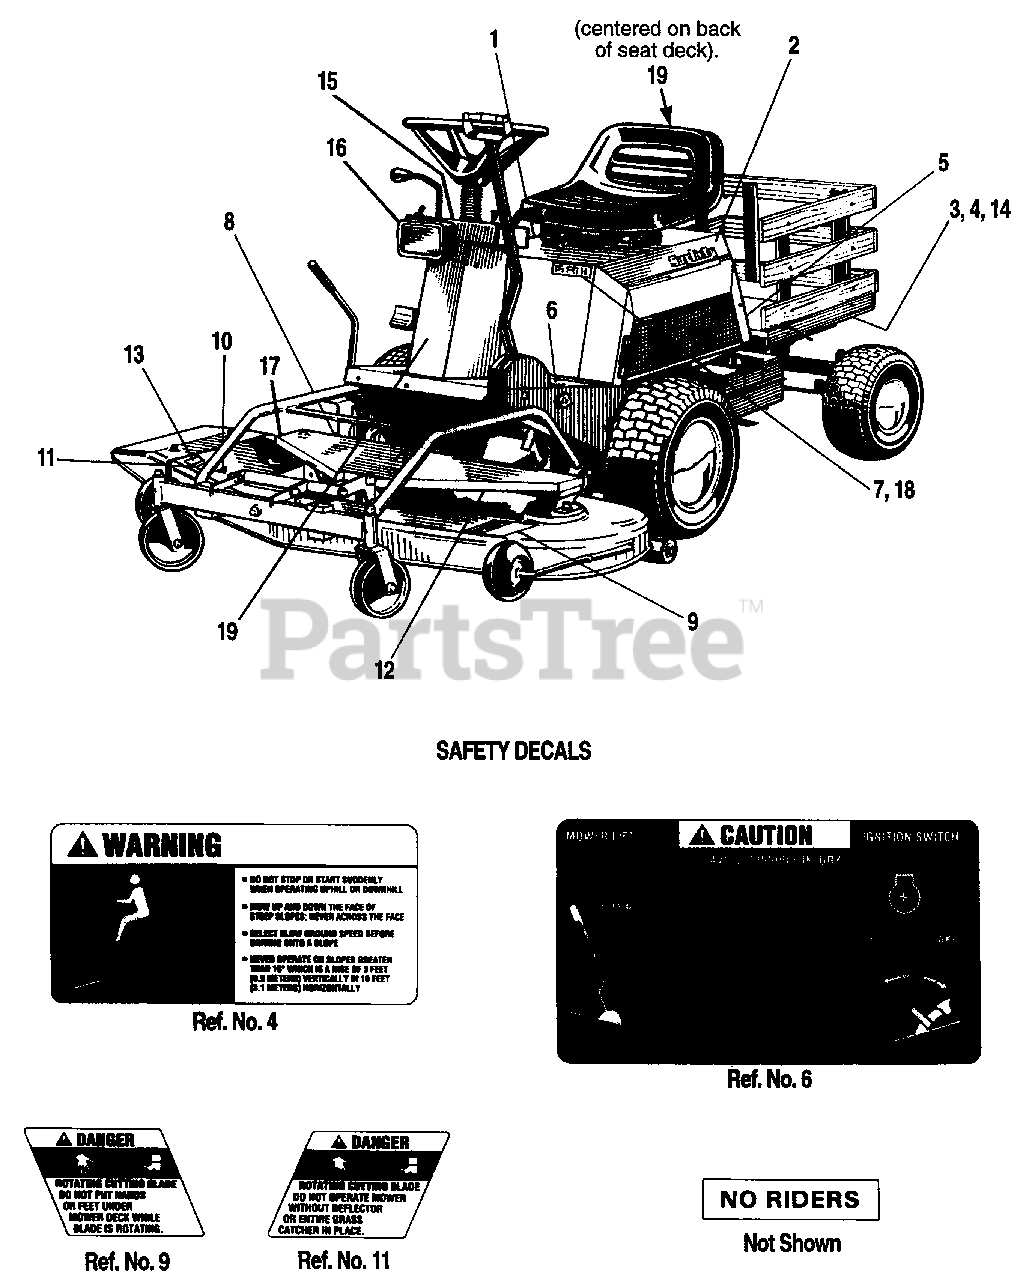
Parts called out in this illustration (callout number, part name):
1	DECAL, Side, LH, 16 (Simplicity)
1	DECAL, Side, LH, 12.5 (Simplicity)
1	DECAL, Side, LH, 16 (AGCO)
1	DECAL, Side, LH, 12.5 (AGCO)
1	DECAL, Side, LH, 16 (Export)
1	DECAL, Side, LH, 16 (Massey Ferguson)
2	DECAL, Side, RH, 16 (Simplicity)
2	DECAL, Side, RH, 12.5 (Simplicity)
2	DECAL, Side, RH, 16 (AGCO)
2	DECAL, Side, RH, 12.5 (AGCO)
2	DECAL, Side, RH, 16 (Export)
2	DECAL, Side, RH, 16 (Massey Ferguson)
3	DECAL, Drive Belts
4	DECAL, Stability
5	TRACTOR I.D. PLATE
6	DECAL, Caution & Controls
7	DECAL, 12 FCH
8	MOWER I.D. PLATE
9	DECAL, Danger
10	DECAL, OPEI
11	DECAL, Danger
12	DECAL, Belt Layout (Under cover)
13	DECAL, 42"
14	DECAL, Paint
15	DECAL, Instrument Panel
16	DECAL, Oil Pressure (12.5 HP & 16 HP)
17	DECAL, Mower Height
18	DECAL, Hydro 16 V-Twin (Export)
19	DECAL, Massey Ferguson
